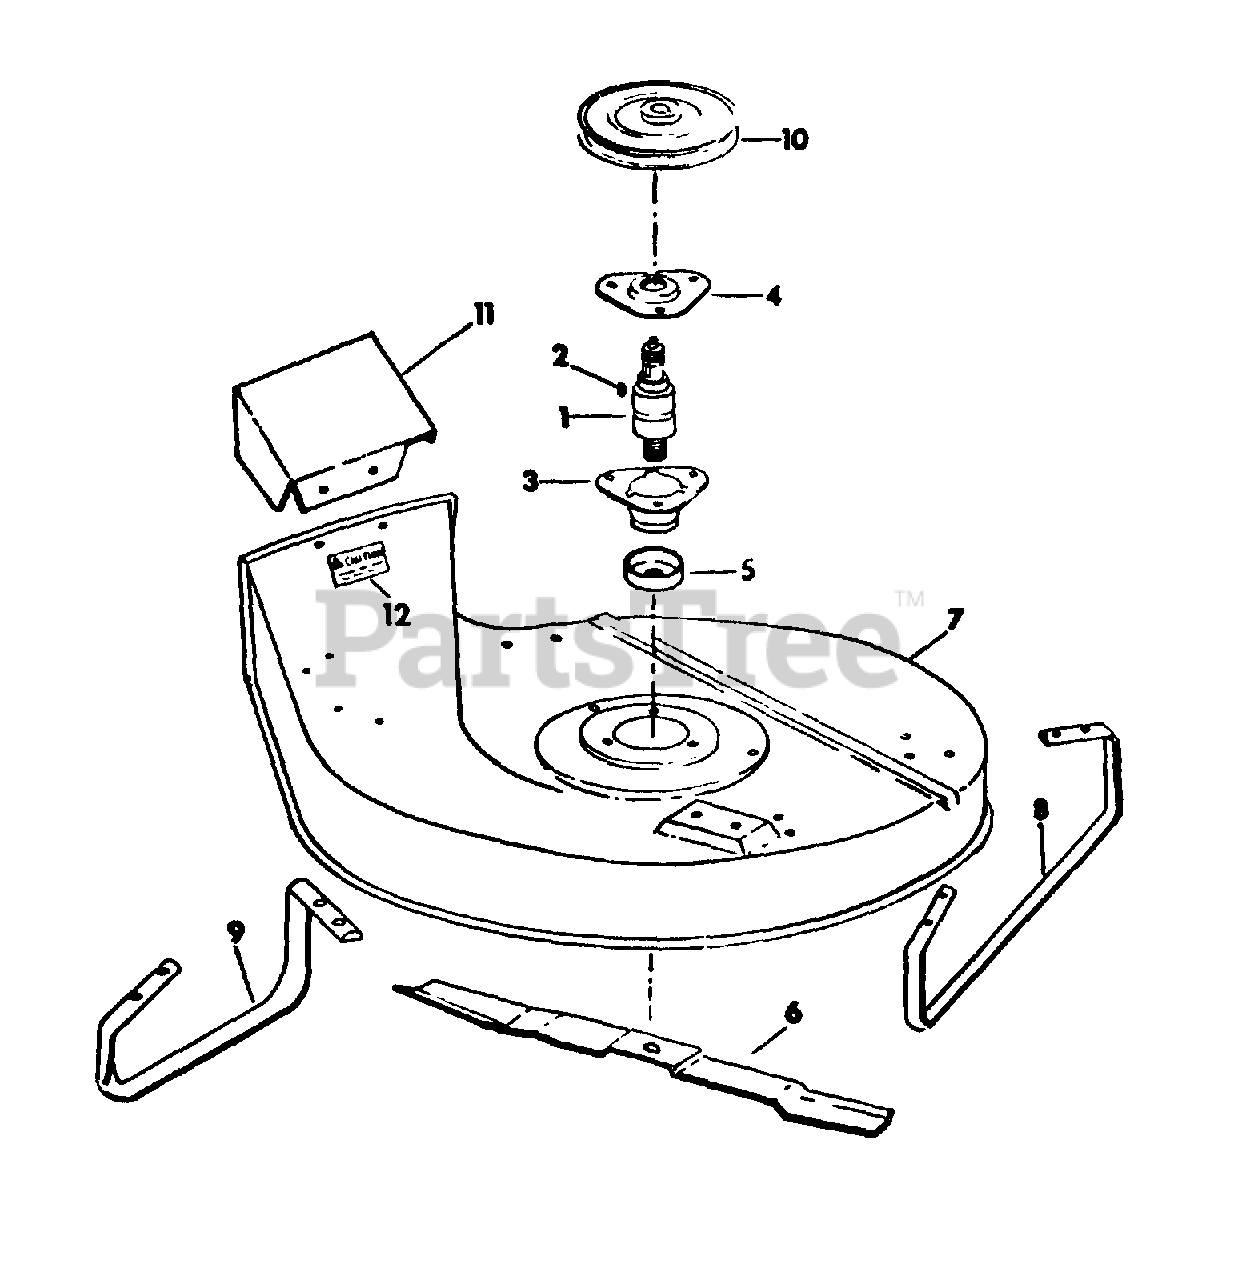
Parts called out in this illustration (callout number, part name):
1	BEARING, BALL AND FAN TYPE
2	KEY, 1/4 X 3/4 WOODRUFF 91
3	HOUSING, SPINDLE
4	CAP, SPINDLE HOUSING
5	CUP, SPINDLE
6	BLADE, 28 IN. MOWER
7	HOUSING ASSY. 28 IN. MOWER
8	RUNNER, LH MOWER
9	RUNNER, RH MOWER
10	PULLEY, CENTER
11	DEFLECTOR, 28 IN MOWER
12	PRODUCT GRAPHIC, CAUTION
